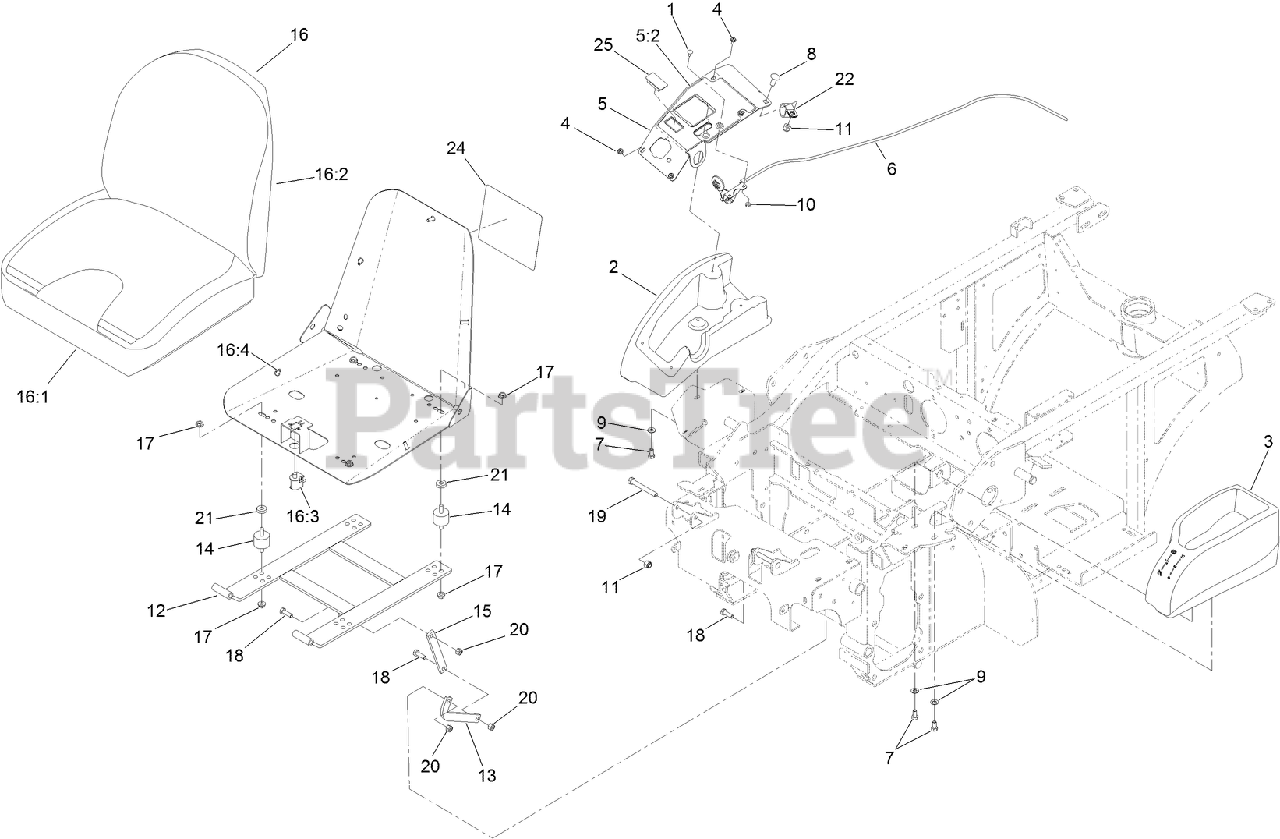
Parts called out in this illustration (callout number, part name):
1	BOLT-CARR
2	CONSOLE-RH
3	CONSOLE-LH
4	SCREW-PPH
5	CONTROL PANEL ASM
5:2	DECAL-CONTROL
6	CABLE-THROTTLE
7	SCREW-HH
8	SCREW-CARR
9	WASHER-PLAIN
10	NUT-LOCK, NI
11	NUT-LOCK, NI
12	FRAME-SEAT
13	LINK-SEAT STOP
14	MOUNT-VIBRATION, RUBBER
15	LINK-SEAT
16	SEAT ASM
16:1	CUSHION-SEAT, BOTTOM
16:2	CUSHION-SEAT, BACK
16:3	SWITCH-BAIL
16:4	BOLT-SEAT
17	NUT-HF
18	SCREW-HH
19	SCREW-HH
20	NUT-LOCK, NI
21	SPACER
22	CLIP-LOOM
24	DECAL-SERVICE AID
25	PLUG-HOLE
